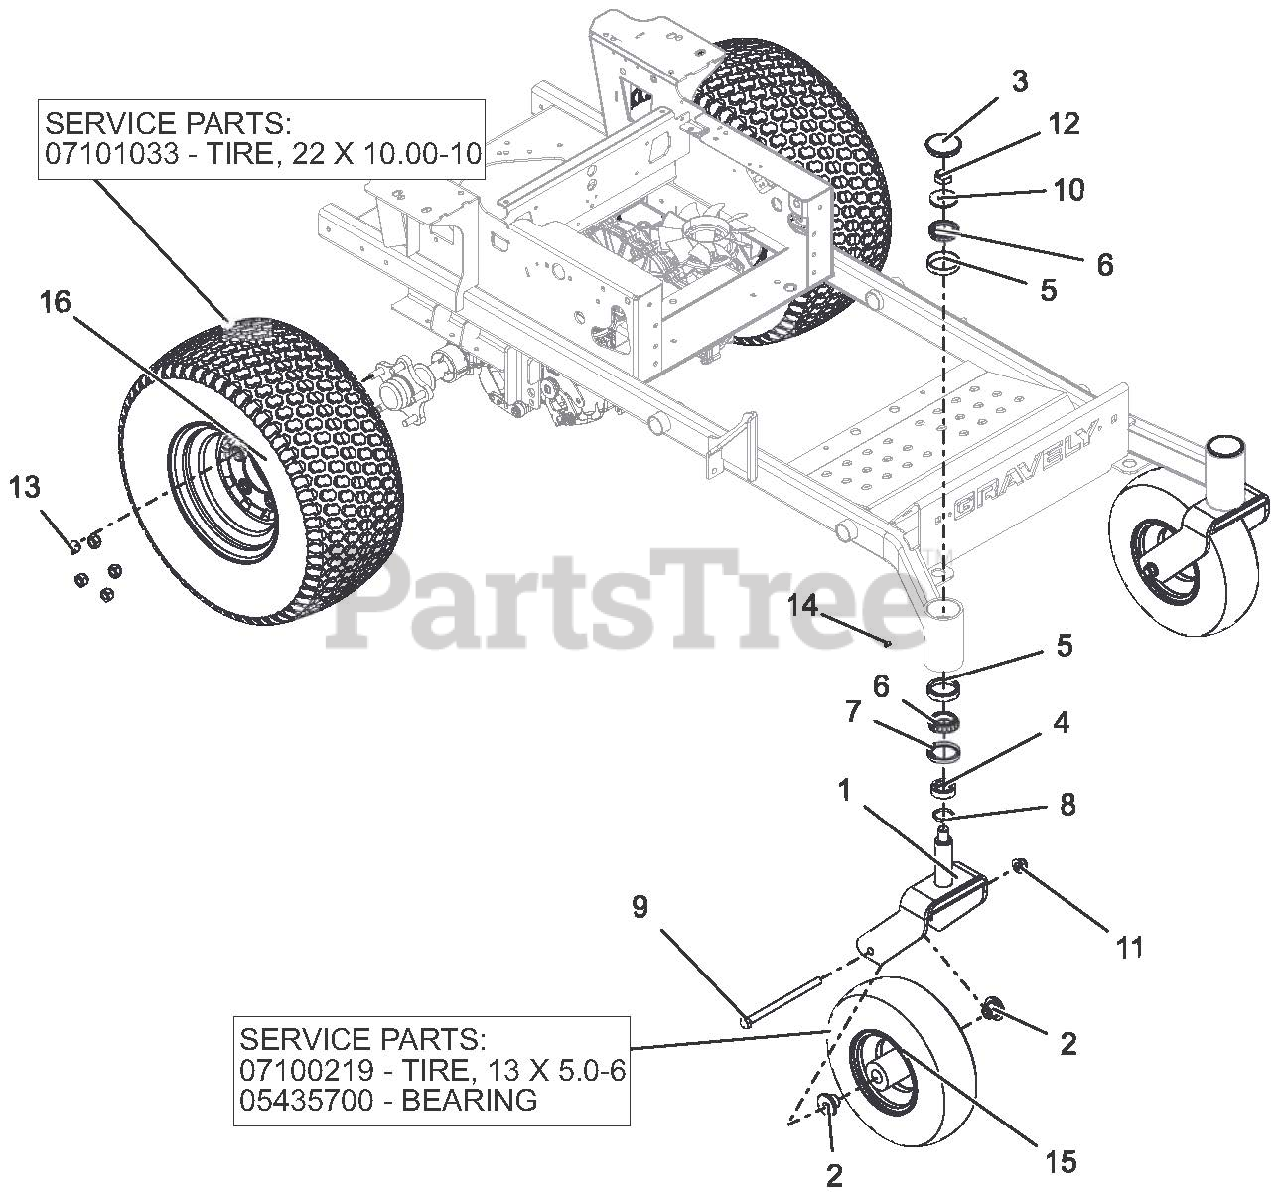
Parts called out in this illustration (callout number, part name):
1	WLDMT, CASTER FORK-RED
2	SPACER, FRONT WHEEL
3	CAP, DUST
4	SPCR, FRONT CASTER FORK
5	BRG, CUP 2.328 X .465
6	BRG, CONE 1.250 X .660
7	SEAL, OIL 1.75 X 2.332 X .312
8	O-RING, 139 W X 1.234 ID
9	BLT-HEX .50-13 X 7.50 GR5 YWZC
10	WSHR-FL-STL .812 X 2.00 X .148 YWZC
11	NUT-LK-NYL-FLG .50-13 YWZC
12	NUT-LK-TOP-JAM .75-16 YWZC
13	NUT, LUG .500-13
14	FITTING, .250-28 FLUSH MOUNT GREASE
15	ASSM TIRE/WHEEL, 13 X 5.0-6
15	TIRE, 13 X 5.0-6
15	BEARING
16	ASSM TIRE/WHEEL, 20 X 10.00-10
16	TIRE, 22 X 10.00-10
